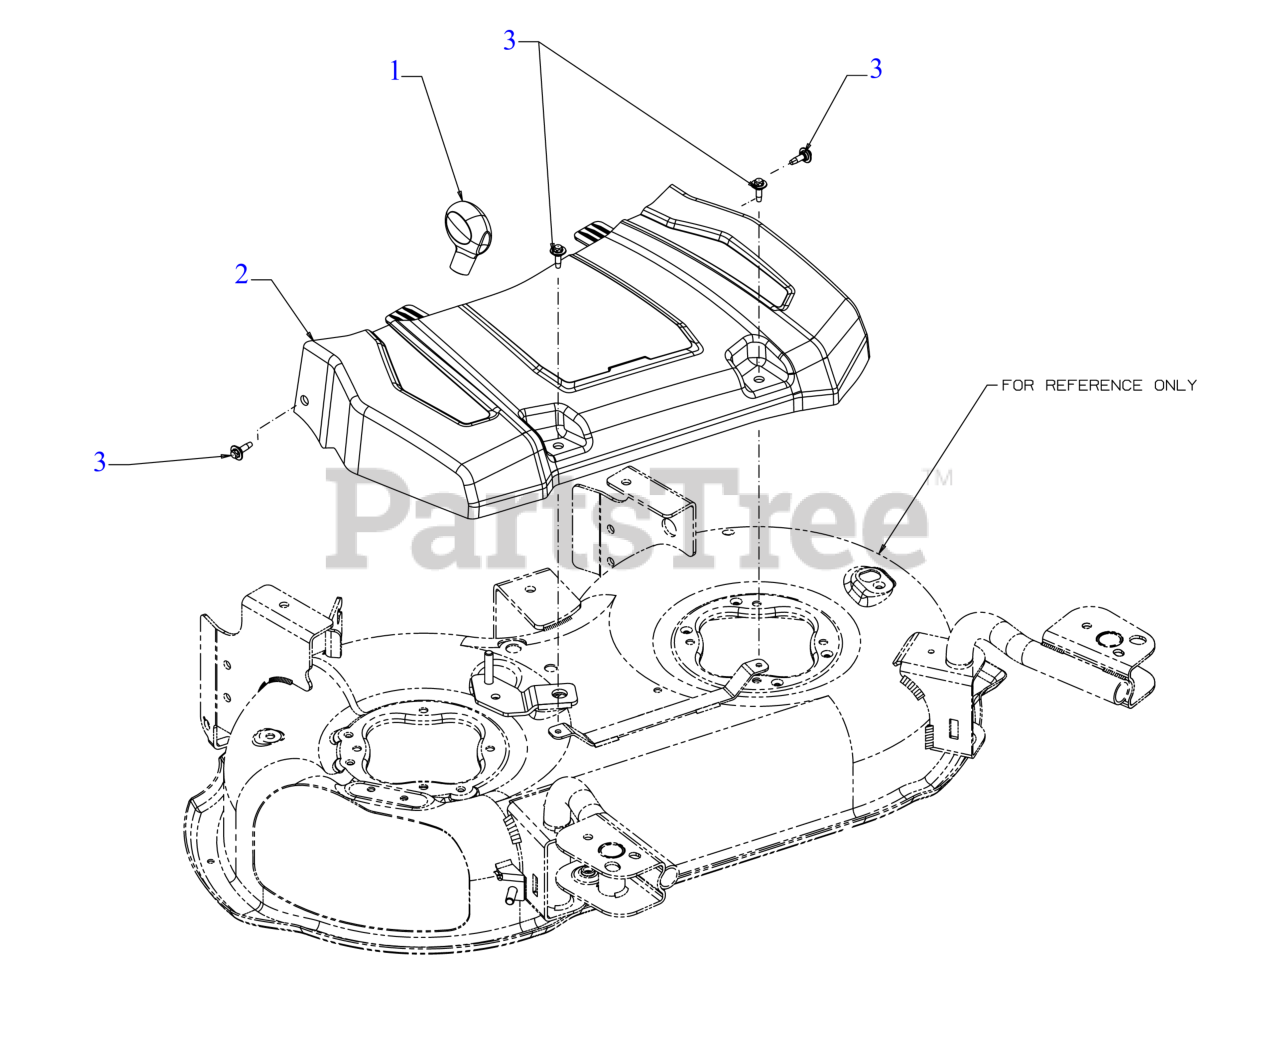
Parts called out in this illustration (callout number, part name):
1	HEIGHT ADJUSTMENT KNOB (SBD GRAY)
2	28" BELT COVER
3	SHOULDER SCREW M6-1 .368 X.115
